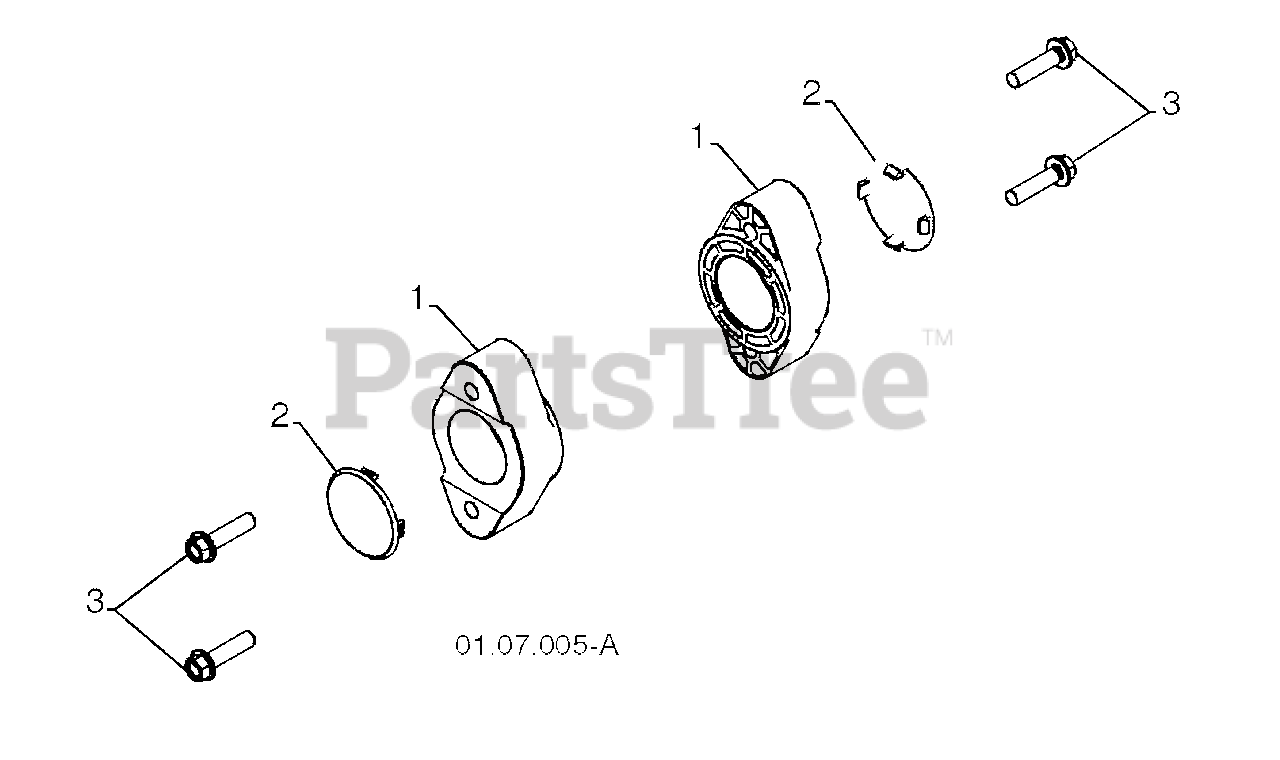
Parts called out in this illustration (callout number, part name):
1	AUGER BEARING
2	BEARING PLUG
3	SCREW 5/16-18 X 1.00
